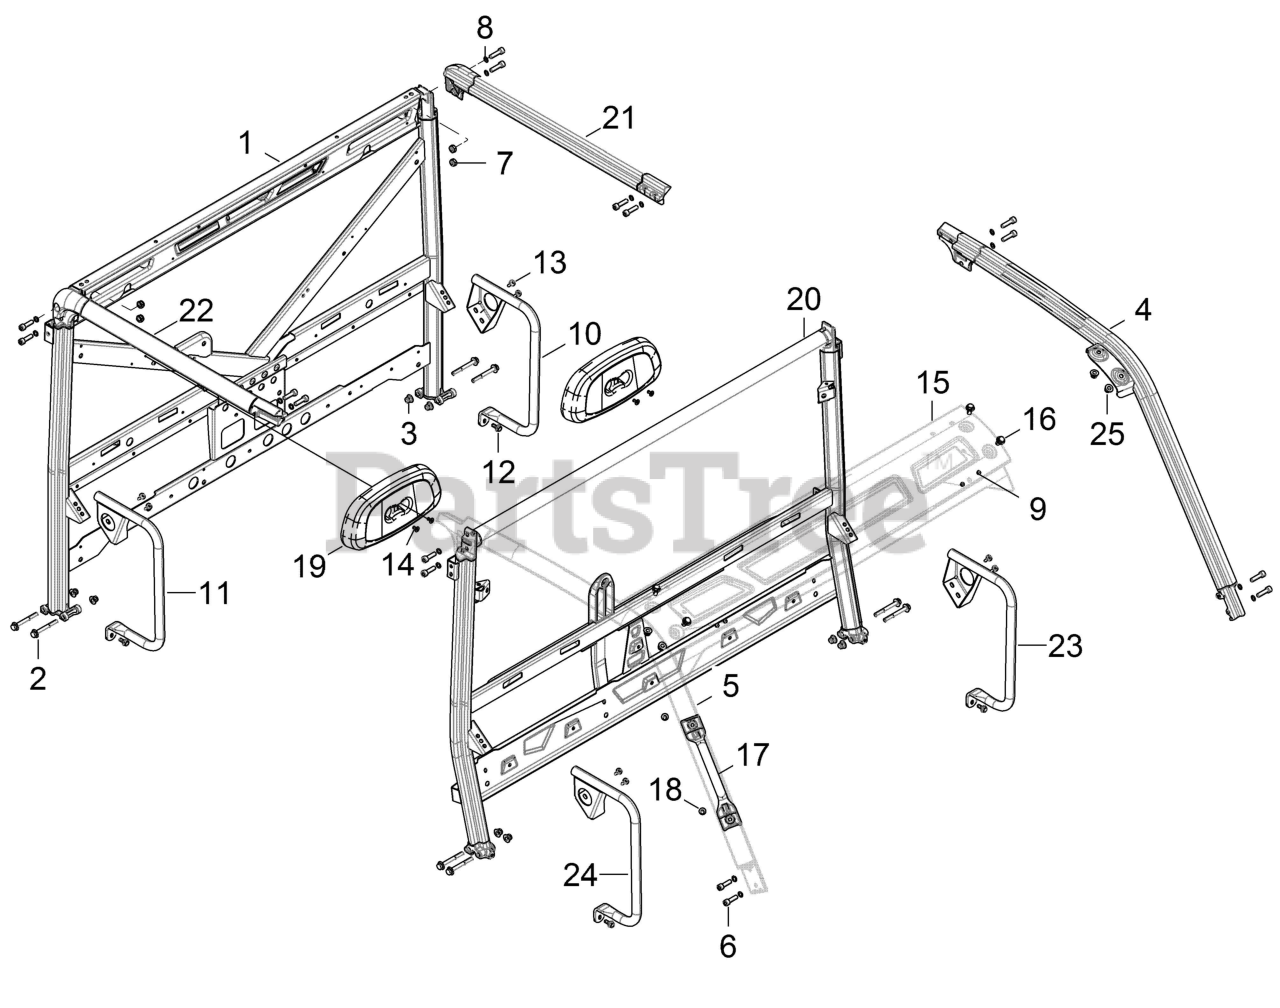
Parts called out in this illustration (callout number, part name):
1	WELD-CAB FRAME,REAR,BLK
2	SCR-HXFL-M10X1.25X80 8.8 ZOD
3	NUT-M10X1.25,FLG,NYLOC-OLIVE D
4	FRONT CAB FRAME, FRONT LH
5	FRONT CAB FRAME, FRONT RH
6	SCR-SH-M10X1.5X35 8.8 ZPB
7	NUT-NYLOC M10X1.5,REF
9	CLIP-PLASTIC,DART
10	HIP BOLSTER, LH
11	HIP BOLSTER, RH
12	SCR-HXFL-M8X1.25X20 8.8 ZOD P3
13	SCR-TXTH-M6X1.0X25 RIE
14	RIVET(50)
15	WELD-PLATE-WNDSHLD,UPR,CAB,BLK
16	BOLT-M10X1.5X20,HXFLG,W/PATCH
17	HANDLE-GRAB,ROPS,BLK
18	BOLT-M8X1.25X20,HXFLG,TAP/R-OD
19	HEADREST-GRAVELY,GRAY
20	WELD-CAB FRAME,CENTER 6 PASS
21	WELD-CAB FRAME,REAR,LH,M.BLK
22	WELD-CAB FRAME,REAR,RH,M.BLK
23	HIP BOLSTER FRONT: 219
24	HIP BOLSTER FRONT: 219
25	NUT-M10X1.25,FLG,NYLOC-OLIVE D
